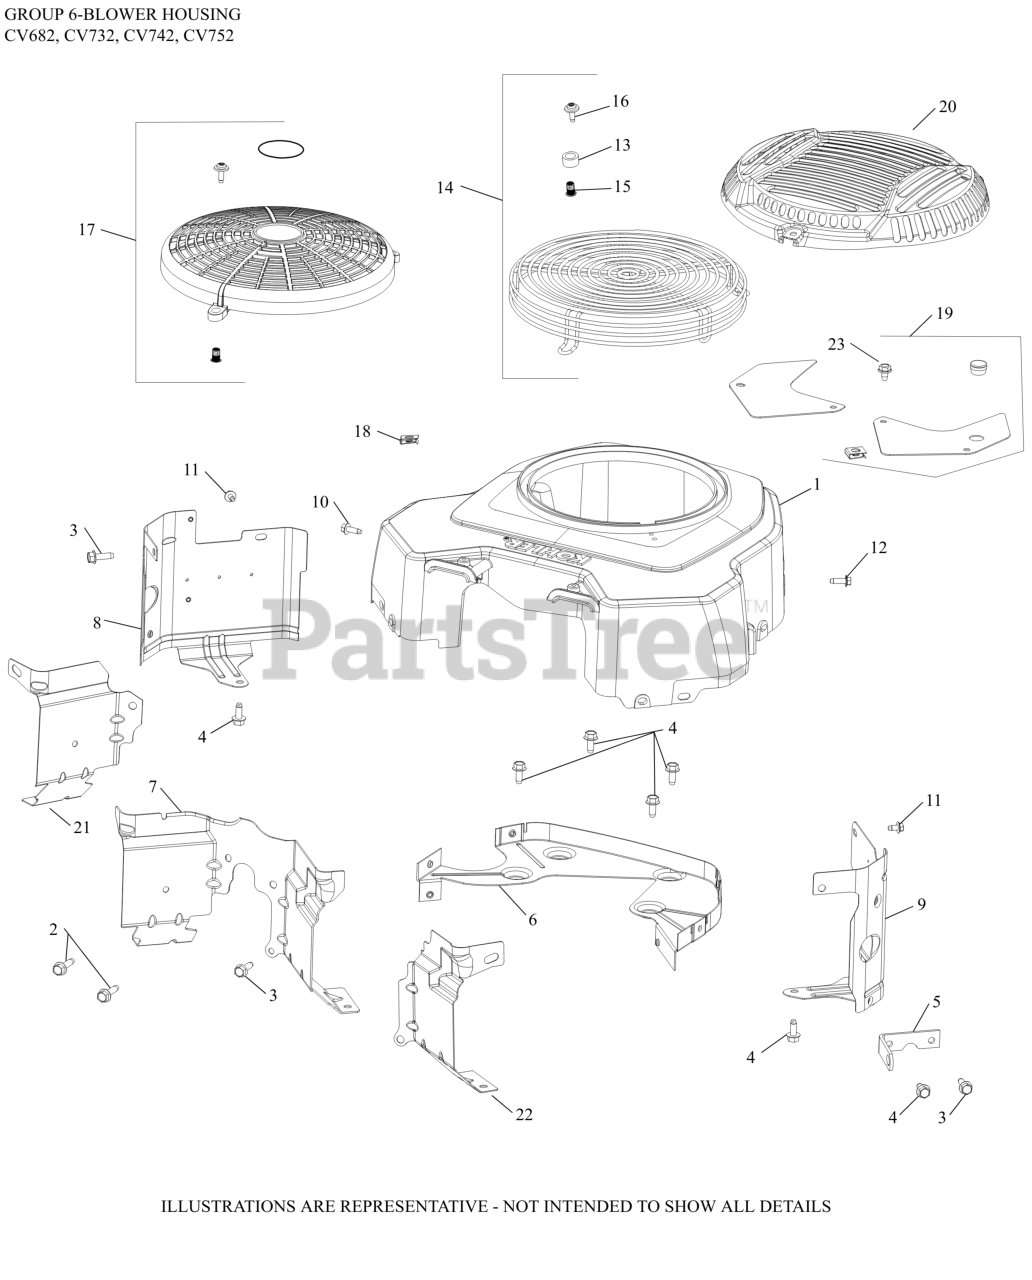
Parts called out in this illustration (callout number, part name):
1	HOUSING, BLOWER
2	SCREW, THREAD FORMING
3	SCREW, THREAD FORMING
4	SCREW, THREAD FORMING
5	STRAP, LIFT
6	KIT, BACKING PLATE
8	KIT, CYL BAFFEL #1 SIDE
9	BAFFLE, LEFT BARREL
10	SCREW, THREAD FORMING
11	SCREW, THREAD FORMING
12	SCREW, THREAD FORMING
14	INSERT, THREADED (M5)
16	SCREW, SEMS
17	KIT, FIXED GUARD
